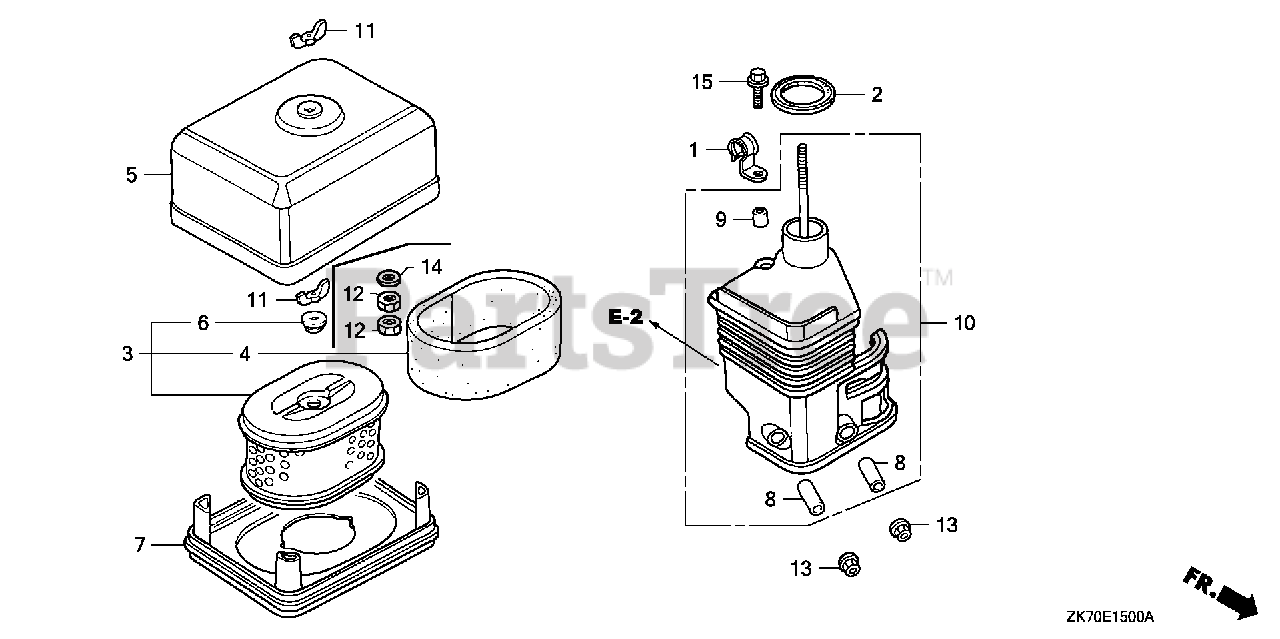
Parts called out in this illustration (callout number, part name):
2	GASKET, ELBOW
3	ELEMENT, AIR CLEANER (DUAL)
4	FILTER (OUTER)
5	COVER, AIR CLEANER (DUAL)
6	GROMMET, AIR CLEANER
8	COLLAR, AIR CLEANER
9	COLLAR B, AIR CLEANER
10	ELBOW, AIR CLEANER
11	WINGNUT, TOOL BOX SETTING
13	NUT, FLANGE (6MM)
15	BOLT, FLANGE (6X20)
